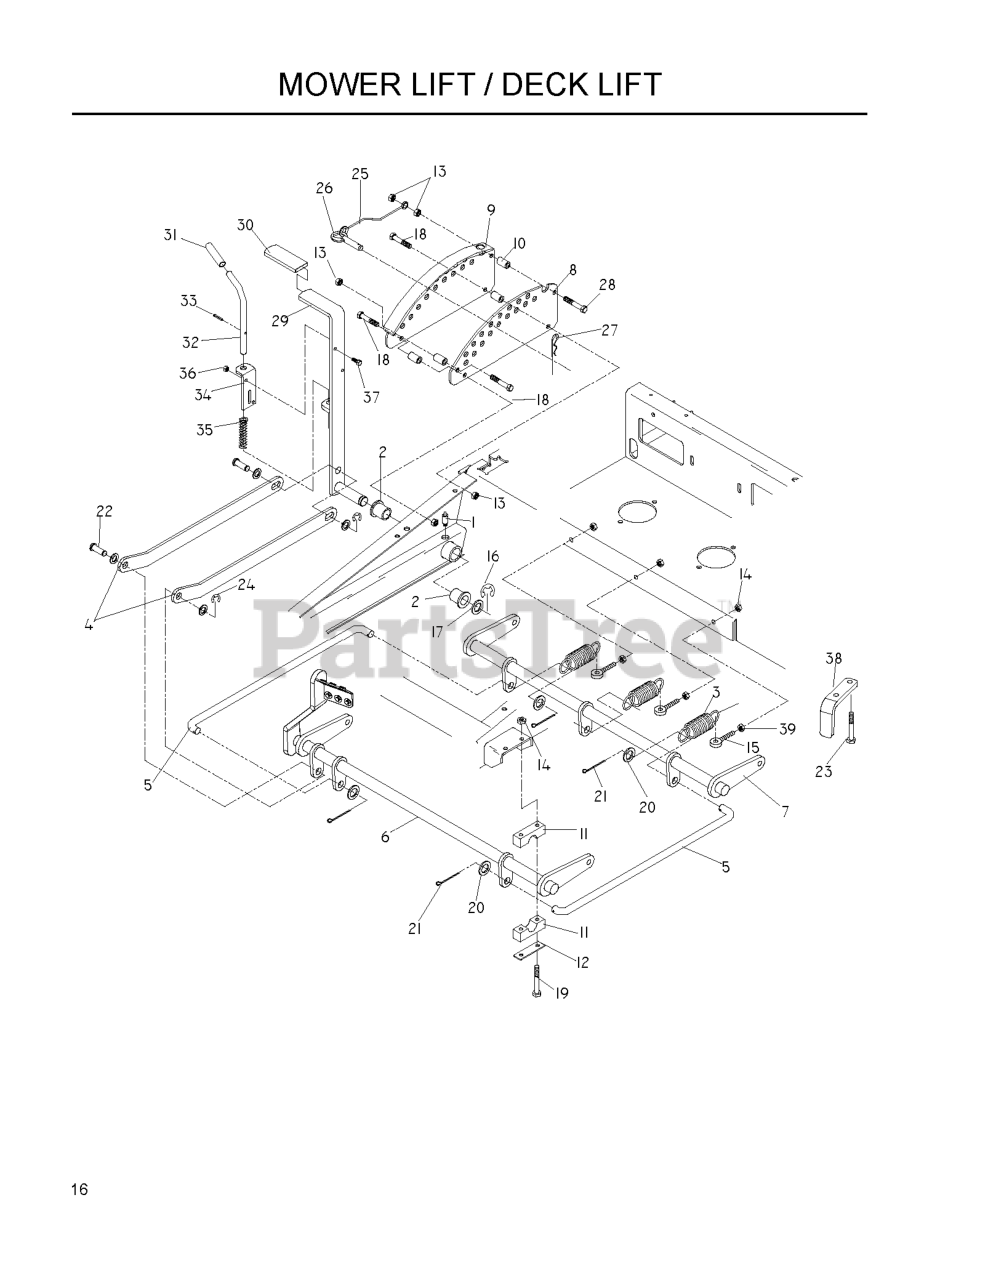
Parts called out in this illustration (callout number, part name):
1	GREASE ZERK LONG
2	BUSHING, FLANGED
3	DECK LIFT SPRING
4	LIFT LINKAGE,PAINTED
5	CONNECTING LINK
6	LIFT SHAFT ASM, FRONT
7	SHAFT LIFT REAR
8	ADJ. PLATE PAINTED
9	ADJ. PLATE WLDMNT
10	DECK LIFT SPACER
11	PILLOW BLOCK
12	REINFORCEMENT BAR
13	NUT 3/8-16 NYLOC
14	NUT 5/16 NYLOC
15	EYEBOLT, RH
16	E-RING 7/8
17	BSHG .875 X 1.375 X .074 ZD
18	HCS 3/8C X 2 1/2
19	HCS 5/16C X 2-3/4
20	WASHER 5/8 FLAT
21	COTTER PIN
22	CLEVIS PIN
23	BOLT 3/8-16 X 1.0
24	E-RING 5/8
27	HAIRPIN #4
28	SCREW 3/8C X 2 3/4 HEX CAP
29	LIFT LEVER WELDMENT
34	PIN MT, UPPER
36	NUT 1/4C CENTER LOCK
37	HCS 1/4C X 3/4 HCS
39	NUT 5/16C WHIZ
